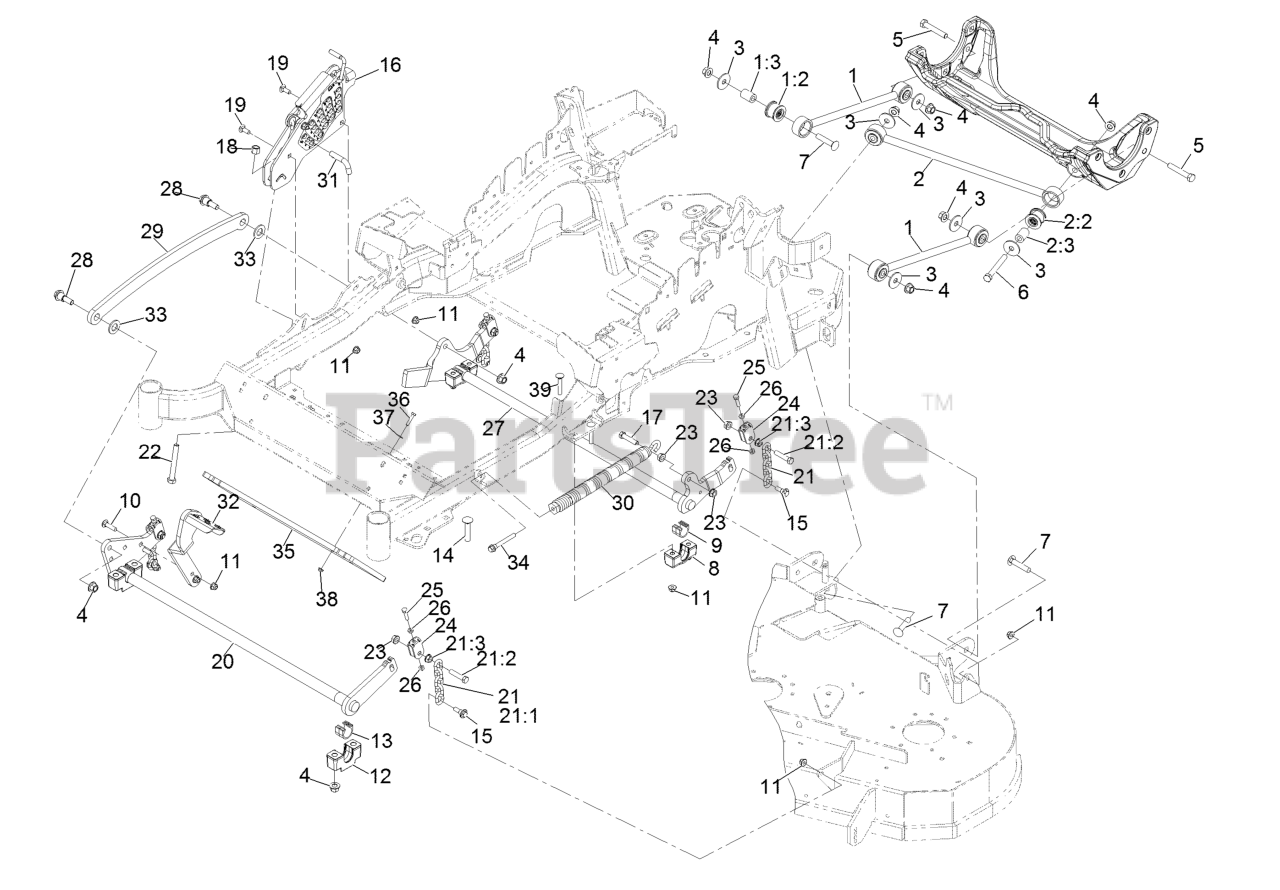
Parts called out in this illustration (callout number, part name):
1	Deck Strut ASM
1:2	Bushing-Suspension,Rubber
2	Panhard Rod ASM
2:2	Bushing-Suspension,Rubber
4	Nut-Lock 1/2-13
5	Screw-HH 1/2-13 X 3
6	Screw-HH 1/2-13 X 4
7	Bolt-Carriage 1/2-13 X 2 1/2
8	Support-Cross Shaft,Bearing Rear
9	Bearing-Cross Shaft, Rear
10	Bolt-Carriage 3/8-16 X 1 1/2
11	Nut-Nyloc 3/8-16 Flg
12	Support-Cross Shaft,Bearing Rear
13	Bearing-Cross Shaft, Front
14	Bolt-Carriage 1/2-13 X 2 1/2 Spl Neck
15	Screw-Hex Flange 3/8-16 X .80
16	HOC ASM
17	Screw-HH 7/16-14 X 2
18	Nut-Nyloc 1/2-13
19	Bolt-Carriage 3/8-16 X 1
20	Decklift-Front
21	Deck Lift Chain ASM
21:1	Chain-Lift, Deck
21:2	Screw-HH 7/16-14 X 2
21:3	Nut-Whizlock 7/16-14
22	Bolt-HH 1/2-13 X 4 Tap
23	Nut-Whizlock 7/16-14
24	Yoke-Adjust, Deck
25	Screw-HH 5/16-18 X 1 1/4
26	Nut-Jam 5/16-18
27	Lift-Deck, Rear
28	Screw-Shoulder HHF 1/2-13 X 1.12
29	Link-Lift, Deck
30	Sub-Contract Bom
30	Spring-Extension
31	Pin-HOC
32	Lever-Foot
33	Washer-3/4 SAE
34	Screw-Shcs 3/8-16 X 2.212
35	Weight-Toe Board
36	Screw-HH 1/4-20 X 1 1/4
37	Washer-1/4 SAE
38	Nut-Nyloc 1/4-20 Flg
39	Bolt-Carriage 3/8-16 X 2 1/4
